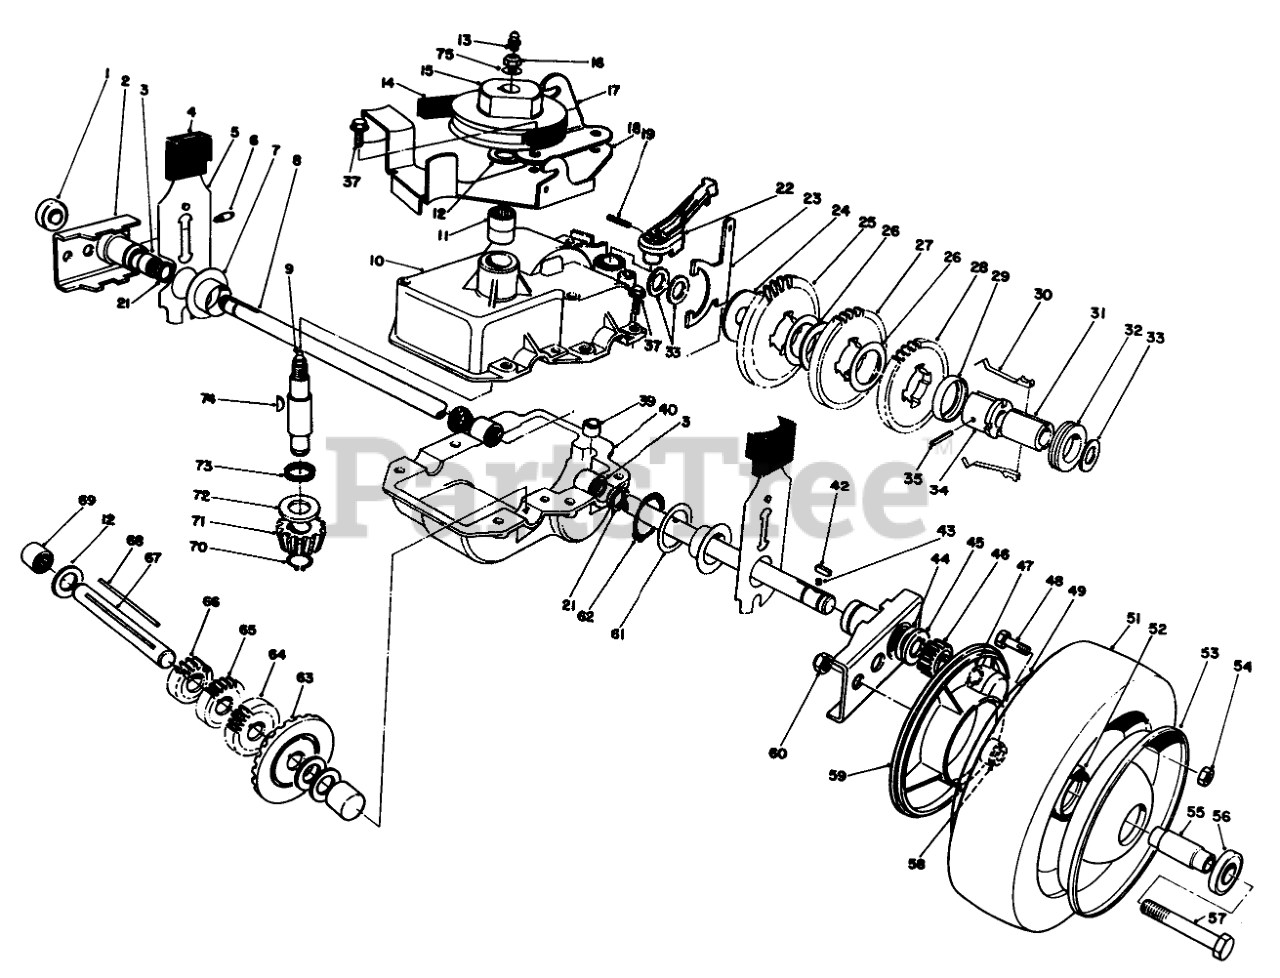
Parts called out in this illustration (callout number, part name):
1	BEARING-WHEEL
2	Pivot Arm Assembly (Incl. Ref. #1, 3, 6 & 21)
3	BEARING-ROLLER
4	KNOB-ARM
5	REAR SPRING ARM ASM
6	FITTING-GREASE
7	CAP-END
8	SHAFT-OUTPUT
9	Shaft-Input (Incl. Ref. #13)
10	Upper Case Assembly (Incl. Ref. #11 & 73)
11	BEARING-NEEDLE
12	WASHER-THRUST
13	FITTING-GREASE, ZERK
14	V-BELT
15	PULLEY
16	NUT-HEX
17	Bracket-Traction Engage
18	Belt Guide Bracket
19	PIN-COIL
21	SEAL-OIL
22	LEVER-SHIFT
23	YOKE-SHIFT
24	WASHER
26	WASHER
27	GEAR-42T
28	GEAR-38T
29	RETAINER-KEY
30	KEY-SHIFT
31	SLEEVE
32	COLLAR-SHIFT
33	WASHER-PLAIN
34	SLEEVE-GEAR
35	PIN-GROOVE
37	SCREW-HWHTF
39	BUSHING-YOKE
40	CASE-GEAR, LOWER
42	KEY RECTANGULAR
43	SPRING-COMPRESSION
44	WASHER-THRUST, OUTER
45	WASHER-THRUST, OUTER
46	GEAR-PINION
47	RING-RETAINING
48	SCREW-HH
49	Wheel-Half
52	HUB-BEARING
53	Wheel-Half
54	NUT-LOCK, NI
55	SPACER-BEARING
56	BEARING-WHEEL
57	SCREW-HH
58	SPACER-COVER, WHEEL
59	COVER-WHEEL
60	NUT-LOCK, CONE
61	WASHER
62	RING-RETAINING
63	GEAR-BEVEL
64	GEAR-18T
65	GEAR-14T
66	GEAR-12T
67	SHAFT-INTERMEDIATE
69	BEARING-NEEDLE, CLOSED
70	RING-RETAINING
71	PINION-BEVEL
72	WASHER-THRUST
74	KEY-WOODRUFF
75	WASHER-FLAT
